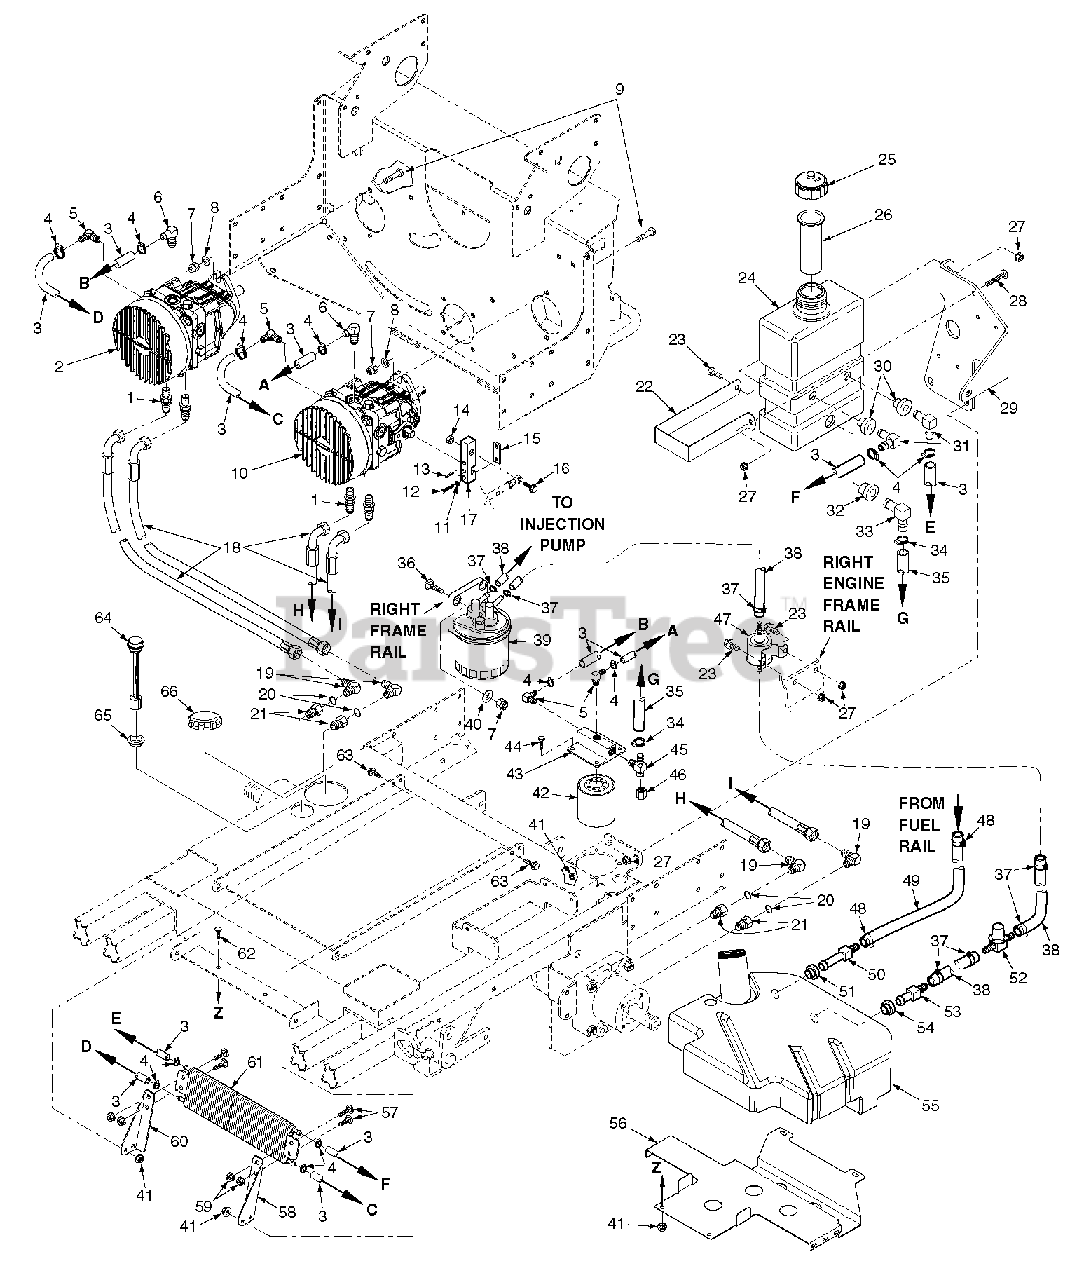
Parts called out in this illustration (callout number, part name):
1	Union, 3/4"-16 JIC x O-Ring
2	Pump, Right Hand, BDP 16A
3	Hose, 3/8" ID Pushlock
4	Hose Clamp, 0.69 dia.
5	Elbow, 90 Deg - 9/16 O-Ring x 3/8" Hose
6	Elbow, 90 Deg - 3/4 O-Ring x 3/8" Hose
7	Nut, Hex Elastic Stop 3/8-16
8	Flatwasher, 3/8" (.391 x .938 x .105)
9	Bolt, Hex Head 3/8-16 x 1.5"
10	Pump, Left Hand, BDP-16A
11	Lockwasher, 1/4" Spring
12	Bolt, Hex Head, 1/4-20 x 1-1/2"
13	Roll Pin, Spring 3/16 x 3/4"
14	Nut, Center Lock 3/8-16
15	Clamp Plate, Pump Control
16	Bolt, Hex Head, 3/8-16 x 1-3/4"
17	Block, Pump Control
18	Hose Assembly, Pump
19	Elbow, 90 Degree, 7/8-14 THD
20	O-Ring
21	Bushing, 7/8-14 JIC x 3/4-16 O-Ring
22	Strap, Hydraulic Tank
23	Bolt, Hex Head 1/4-20 x 3/4"
24	Oil Reservoir Assembly
25	Cap, Hydraulic Tank
26	Insert, Filler Neck
27	Nut, Hex Elastic Stop 1/4-20
28	Screw, Phillips Head, 1/4-20
29	Support Bracket, Hydraulic Tank
30	Bushing, .56 Dia. Viton
31	Elbow, 90 Degree .38 Hose
32	Bushing, .78 Dia. Viton
33	Elbow, 90 Degree
34	Clamp, Hose
35	Hose Assembly, 1/2" ID (Oil Reservoir to Filter Base)
36	Bolt, Carraige 3/8-16 x 1"
37	Clamp, Fuel Hose 5/16" ID
38	Fuel Hose, 5/16" ID. Non-Perm
39	Fuel Filter
40	Flatwasher, 3/8" (.391 x .938 x .105)
41	Nut, Serrated Flange 5/16-18
42	Oil Filter
43	Oil Filter Base
44	Bolt, Hex Head 5/16-18 x1.0" Zinc
45	Tee, 3/4 O-Ring x JIC x 1/2" Hose
47	Fuel Pump, Cat
48	Clamp, 3/16" ID
49	Hose, 3/16" Fuel Line
50	Hose Fitting
51	Bushing
52	Valve, Fuel Shutoff
53	Fitting, Hose with Screen
54	Bushing
55	Fuel Tank Assembly
56	Support Bracket, Fuel Tank
57	Bolt, Carraige 1/4-20 x 3/4"
58	Mounting Bracket - LH, Oil Cooler
59	Nut, Serrated Flange 1/4-20
60	Mounting Bracket - RH, Oil Cooler
61	Oil Cooler
62	Bolt, Carraige 5/16-18 x 3/4"
63	Bolt, Hex Head 5/16-18 x 3/4"
64	Fuel Gauge Assy.
65	Seal, Fuel Gauge
66	Cap, Fuel Tank
